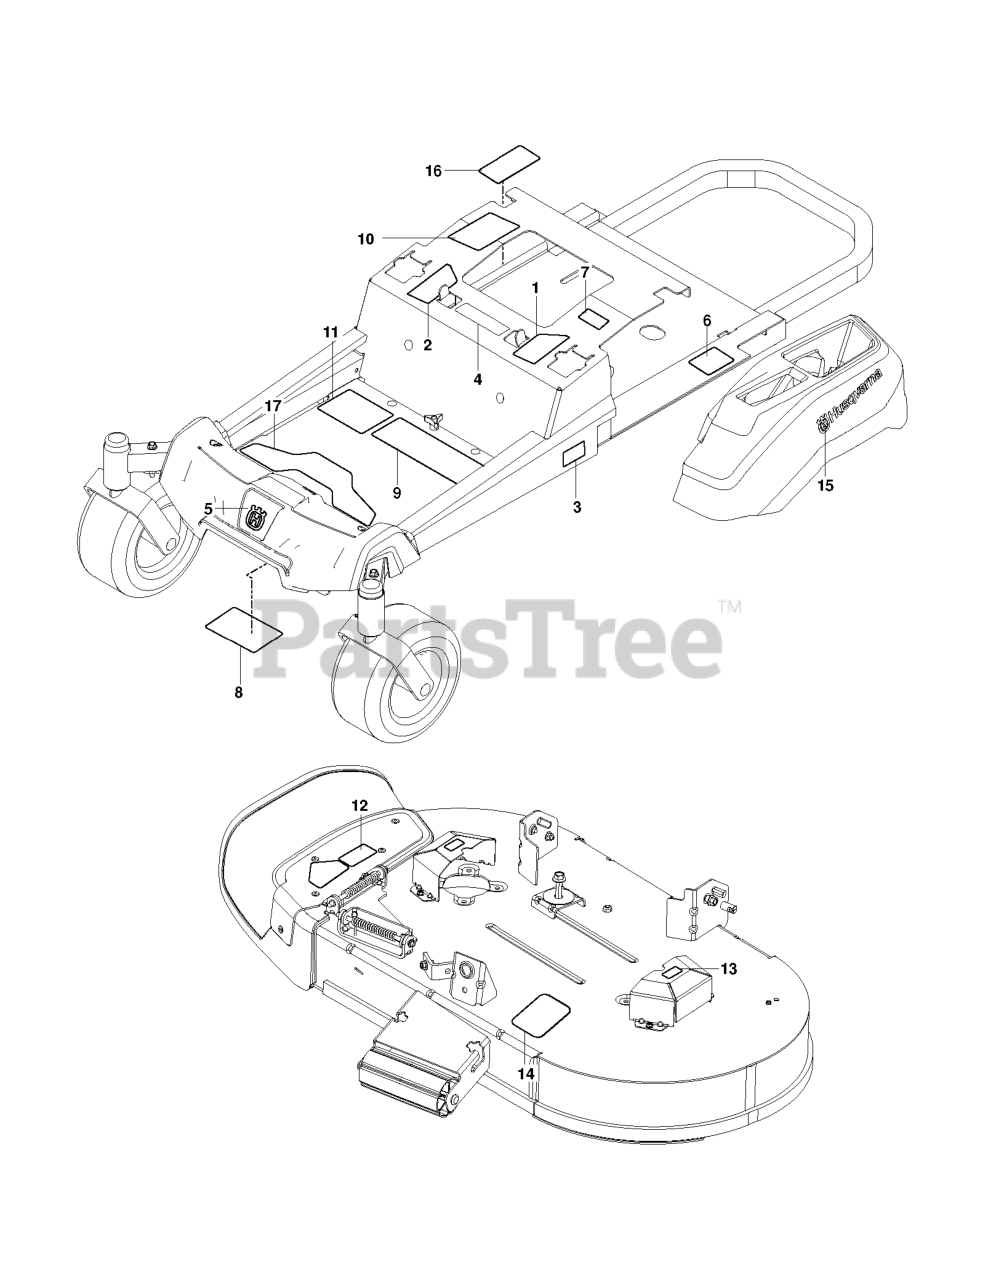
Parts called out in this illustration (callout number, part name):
1	DECAL.ZTR.RZ.THRTL/PRKBRK.V2.L
2	DECAL.ZTR.RZ.THRTL/PRKBRK.V2.R
3	DECAL.ZTR.SIDRAIL.Z242F.HUS
4	EURO DECAL-BATTERY WARNIN6
5	DECAL.BADGE.55MM.CROWNH.HUSQ
6	DECAL, DO NOT TOW
7	DECAL, EXITING MOWER
8	DECAL, SERVICE
9	DECAL, SAFETY WARNING
10	DECAL.WARNING.CUST.RESP.E85.
11	DECAL.ZTR.STRTNGINST.REMOTECHK
12	DECAL.TRACT/ZTR.DECKWARN.JONS
13	DECAL.DECK.6MIL.EURO.NOSTEP
14	DECAL.V-BELT.SCH.42/46"MEC/ELE
15	DECAL.HUSQVARNA.210MM
16	DECAL, WARNING SPARK ARRESTOR
17	PAD.RZ.FOOTREST.PLATE
